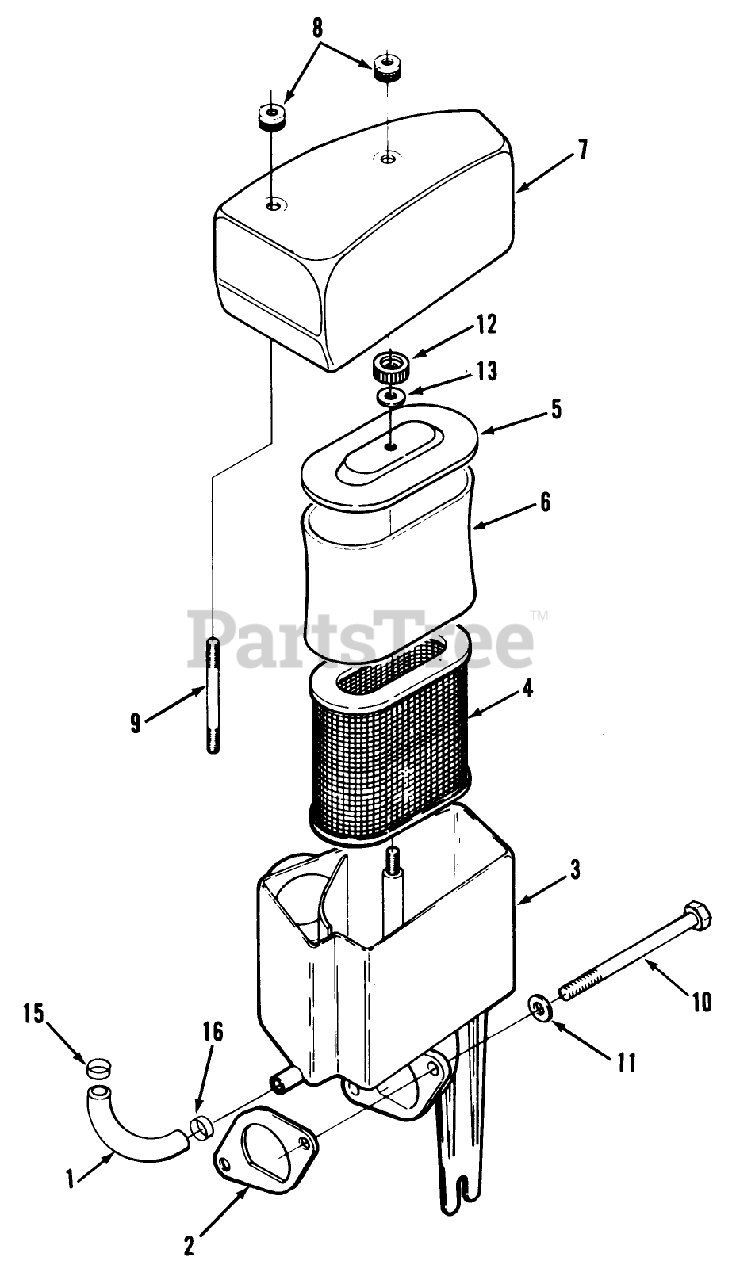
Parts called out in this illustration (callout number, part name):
3	AIR CLEANER ELEMENT
6	WRAPPER-ELEMENT
10	HHCS-M8 X 100MM
16	CLAMP-HOSE
